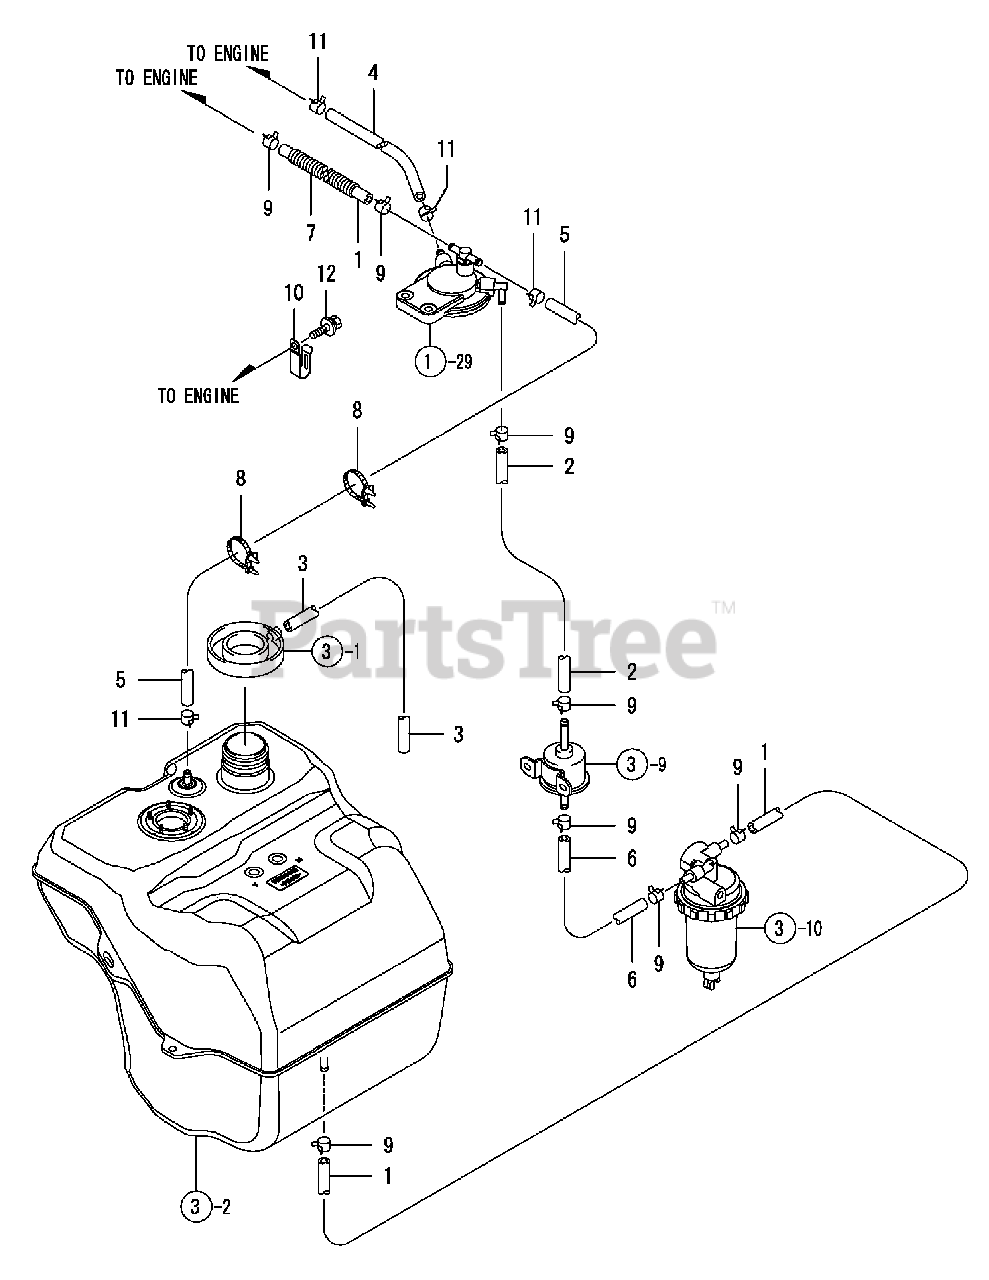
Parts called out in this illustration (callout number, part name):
3	Pipe,Fuel Oil Pan
7	Pipe 13, Corrugat
10	Clamp,Battery Cable
